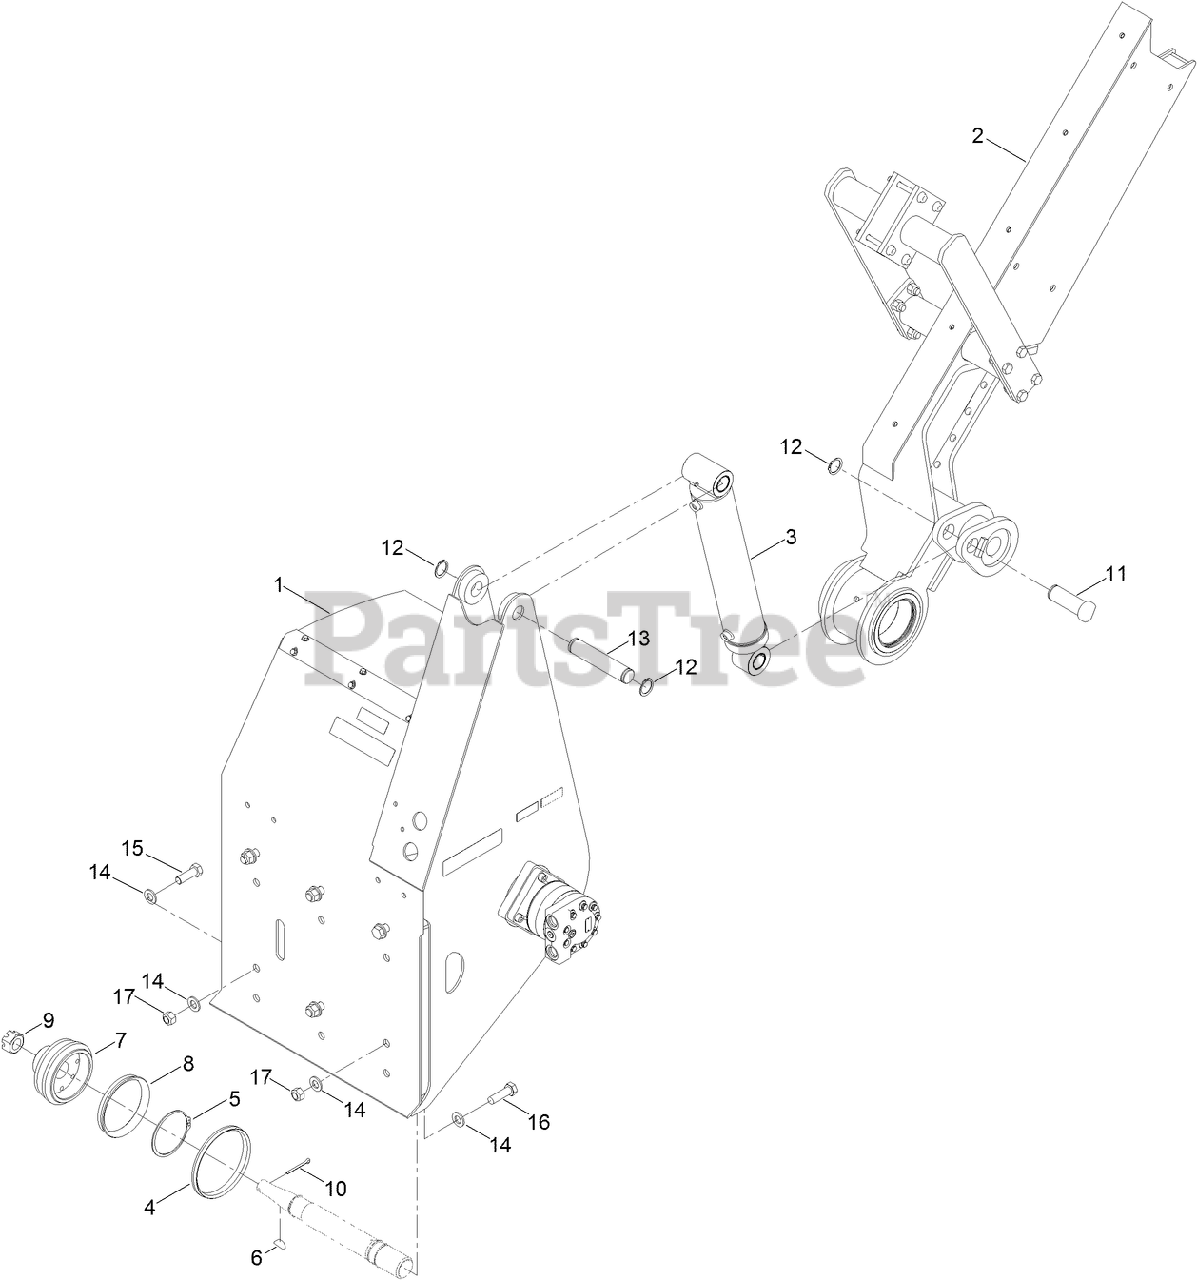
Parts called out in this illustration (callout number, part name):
1	TRENCHER FRAME ASM
2	DIRECT DRIVE BOOM ASM
3	CYLINDER-HYDRAULIC
5	RING-RETAINING, EXTERNAL
6	KEY-WOODRUFF
7	HUB-TRENCHER, DRIVE
8	SEAL-PLANETARY, URETHANE
9	NUT-HEX, SLOTTED
10	PIN-COTTER
11	PIN-HEADED
13	PIN-PLAIN
14	WASHER-Flat
15	SCREW-HH
17	NUT-LOCK
